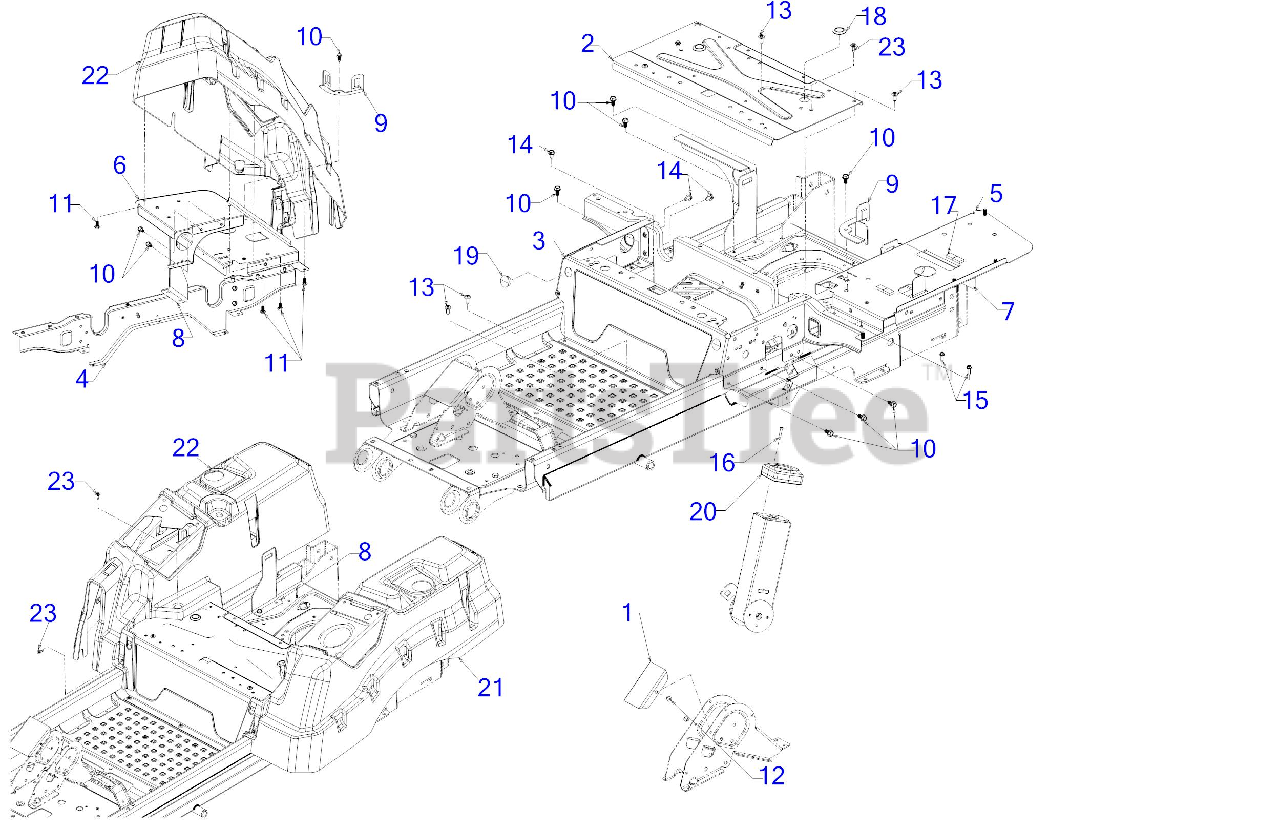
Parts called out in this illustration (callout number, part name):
10	SCREW 5/16-18 x .750
11	SCREW 5/16-14 x .750
12	SCREW 1/4-20 x .5
13	SCREW 5/16-18 x .750
14	SCREW 5/16-18 x .500
15	SCREW 1/4-20 x .750
16	SCREW #10-16 x 1.25
17	FOAM TAPE .625 WIDE x .25 THK BULK
19	PLASTIC PLUG
20	STEERING COLUMN COVER
21	CONSOLE (LH) 2.25" CAP
22	CONSOLE (RH) 2.25" CAP
23	SHOULDER SCREW M6-1 .368 X.115
